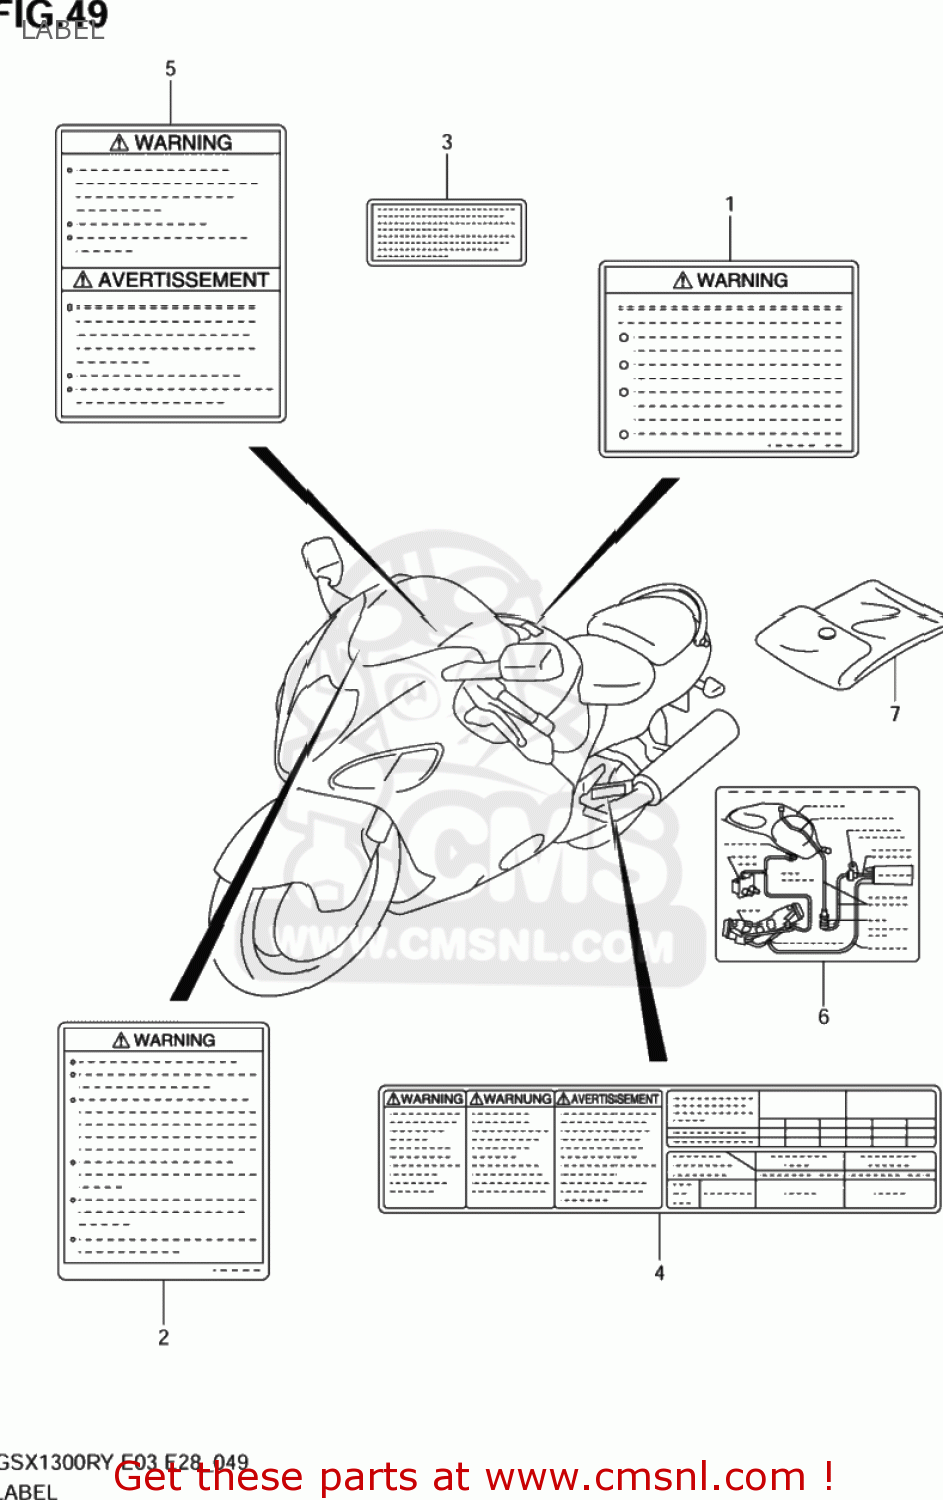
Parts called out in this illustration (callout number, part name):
1	LABEL,GENERAL WARNING
2	LABEL,SCREEN
3	LABEL,MANUAL NOTICE
4	STICKER
5	LABEL,WARNING STEERING
6	LABEL,VACUUM HOSE ROUTING
7	BAG COMP,OWNERS MANUAL
8	MANUAL,OWNER'S
